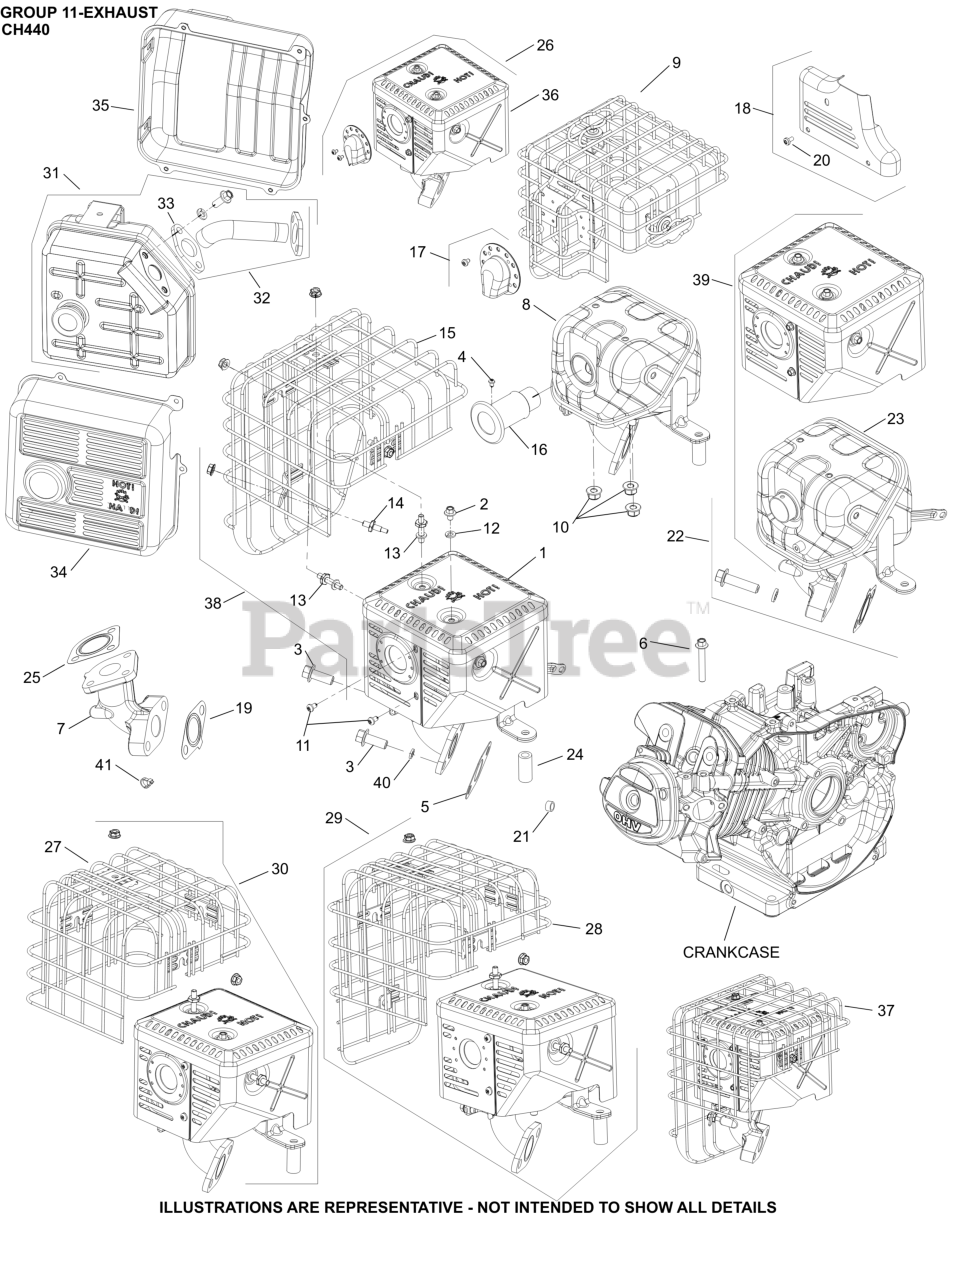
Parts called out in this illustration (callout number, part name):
1	KIT, MUFFLER
3	SCREW, M10 X 40
4	SCREW, SPARK ARRESTOR
7	ELBOW, EXHAUST
10	NUT, HEX FLANGE LOCK (M8)
11	SCREW, M5 X 8, HEX FLANGE HEAD
12	WASHER, LOCK
16	ARRESTOR ASSEMBLY, SPARK
18	KIT, PIPE PROTECTRO SHIELD ASSEMBLY
19	GASKET, EXHAUST
20	SCREW, PIPE PROTECTOR
25	GASKET, MUFFLER
